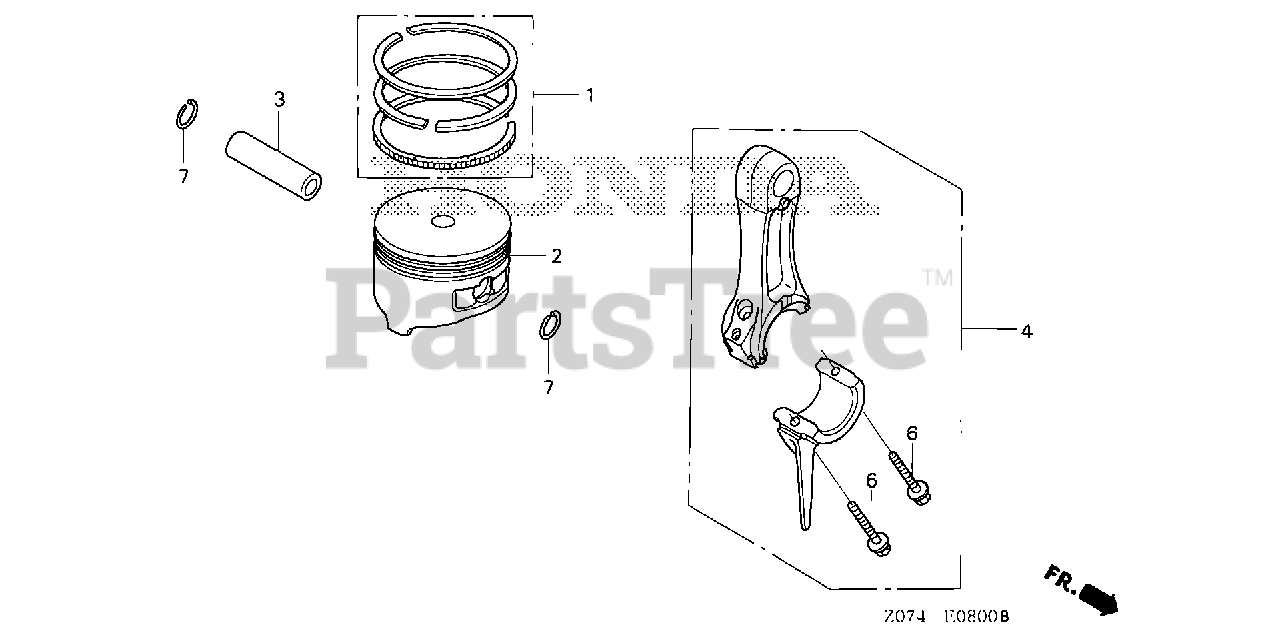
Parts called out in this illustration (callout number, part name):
1	RING SET, PISTON
3	PIN, PISTON
4	ROD ASSY., CONNECTING
4	ROD ASSY., CONNECTING (UNDER SIZE)
6	BOLT, CONNECTING ROD
7	CLIP, PISTON PIN (13MM)
